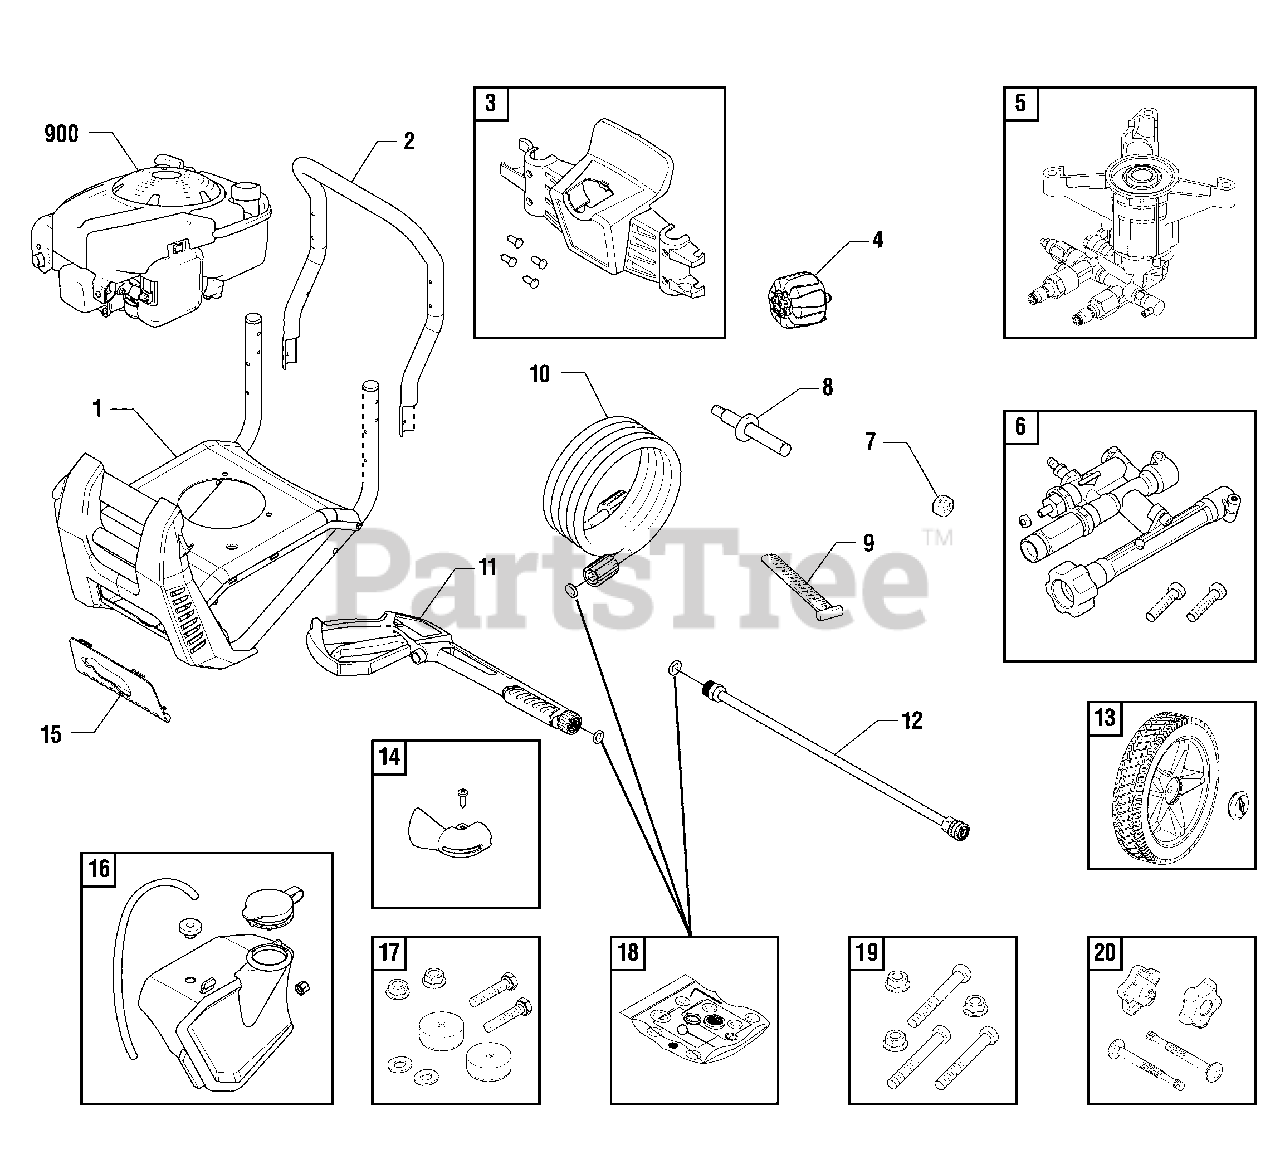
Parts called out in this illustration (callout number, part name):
6	POWERFLOW
11	GUN
14	DEFLECTOR-EXHAUST
16	TANK-CHEMICAL
17	MOUNT-VIBRATION
19	KIT-HARDWARE PUMP MOUNTING
20	KIT-HARDWARE HANDLE
900	** ENGINE
